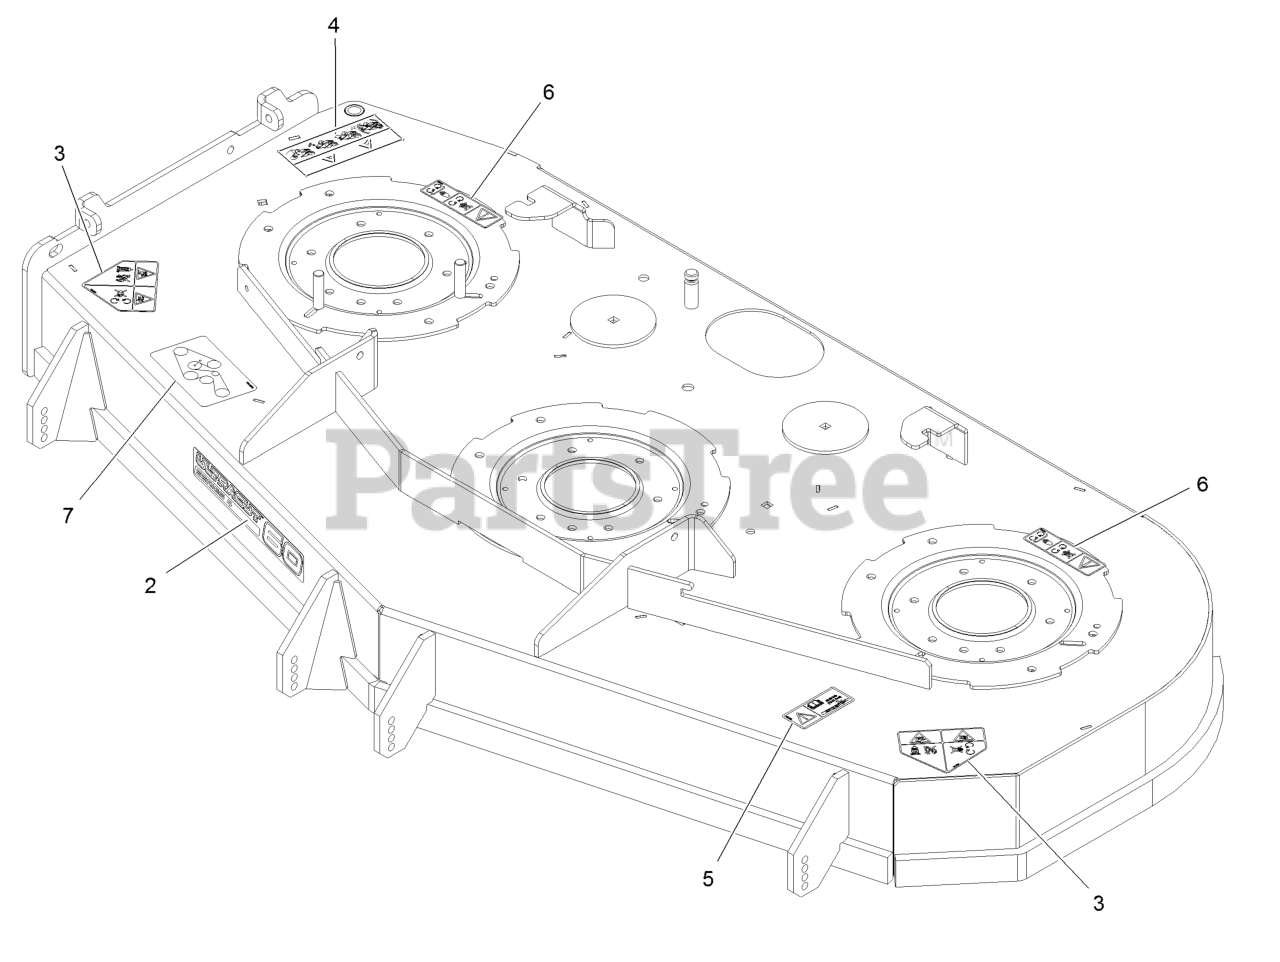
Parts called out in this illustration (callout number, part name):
2	Decal, 604
3	Decal-Danger
4	Decal-Warning, Bagger
5	Decal-Bolt Torque
6	Decal-Cover, Missing
7	Decal-Belt Routing
